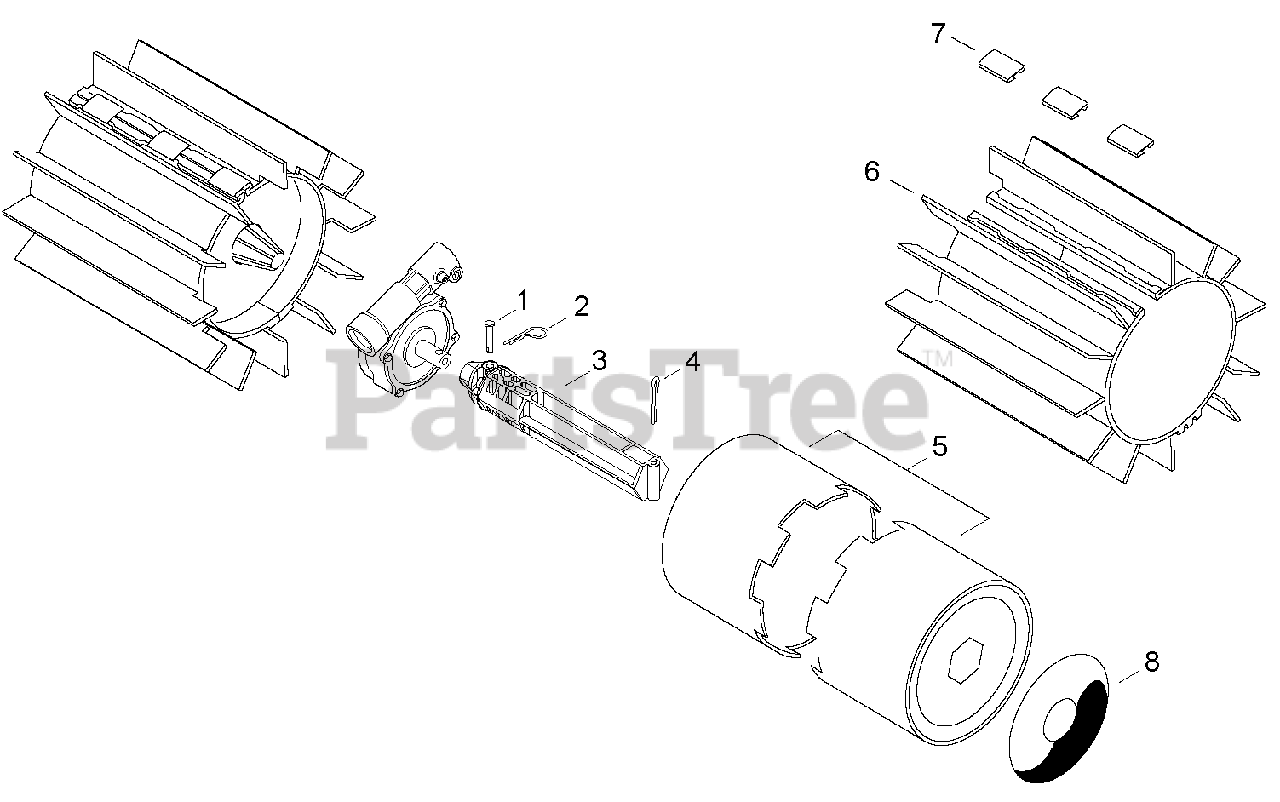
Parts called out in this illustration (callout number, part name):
1	PIN, CLEVIS
2	PIN, HITCH
3	AXLE, DRUM
4	PIN, COTTER
5	HUB, DRUM
6	BELT, SWEEPER
7	CLIP, BELT
8	LABEL, POWERBROOM
